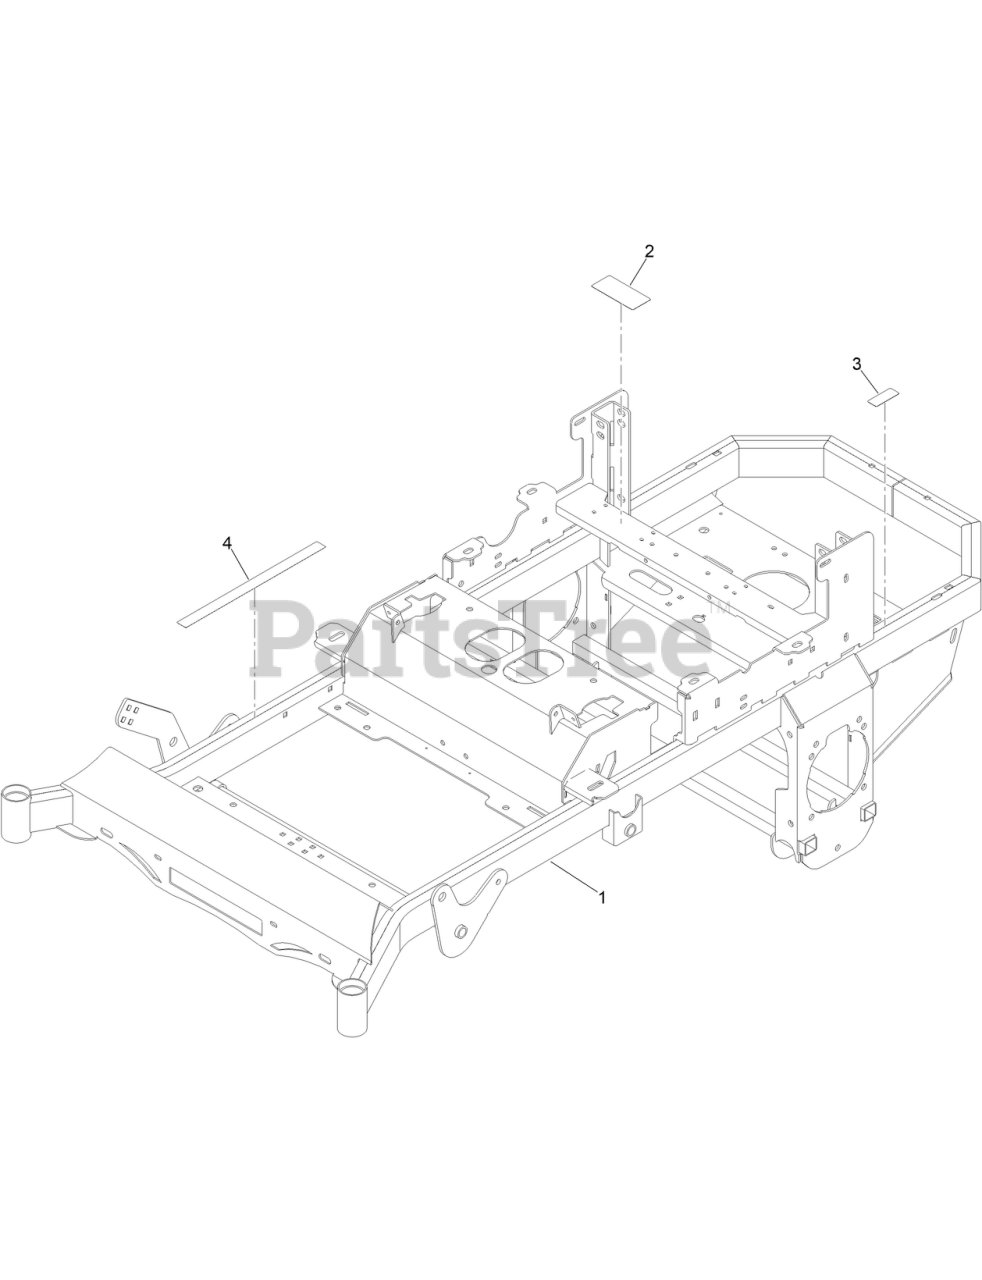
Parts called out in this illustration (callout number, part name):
1	FRAME ASM
2	DECAL-ROTATING FAN HAZARD
3	DECAL-HOT SURFACE
4	DECAL-WARNING(AURORA)
